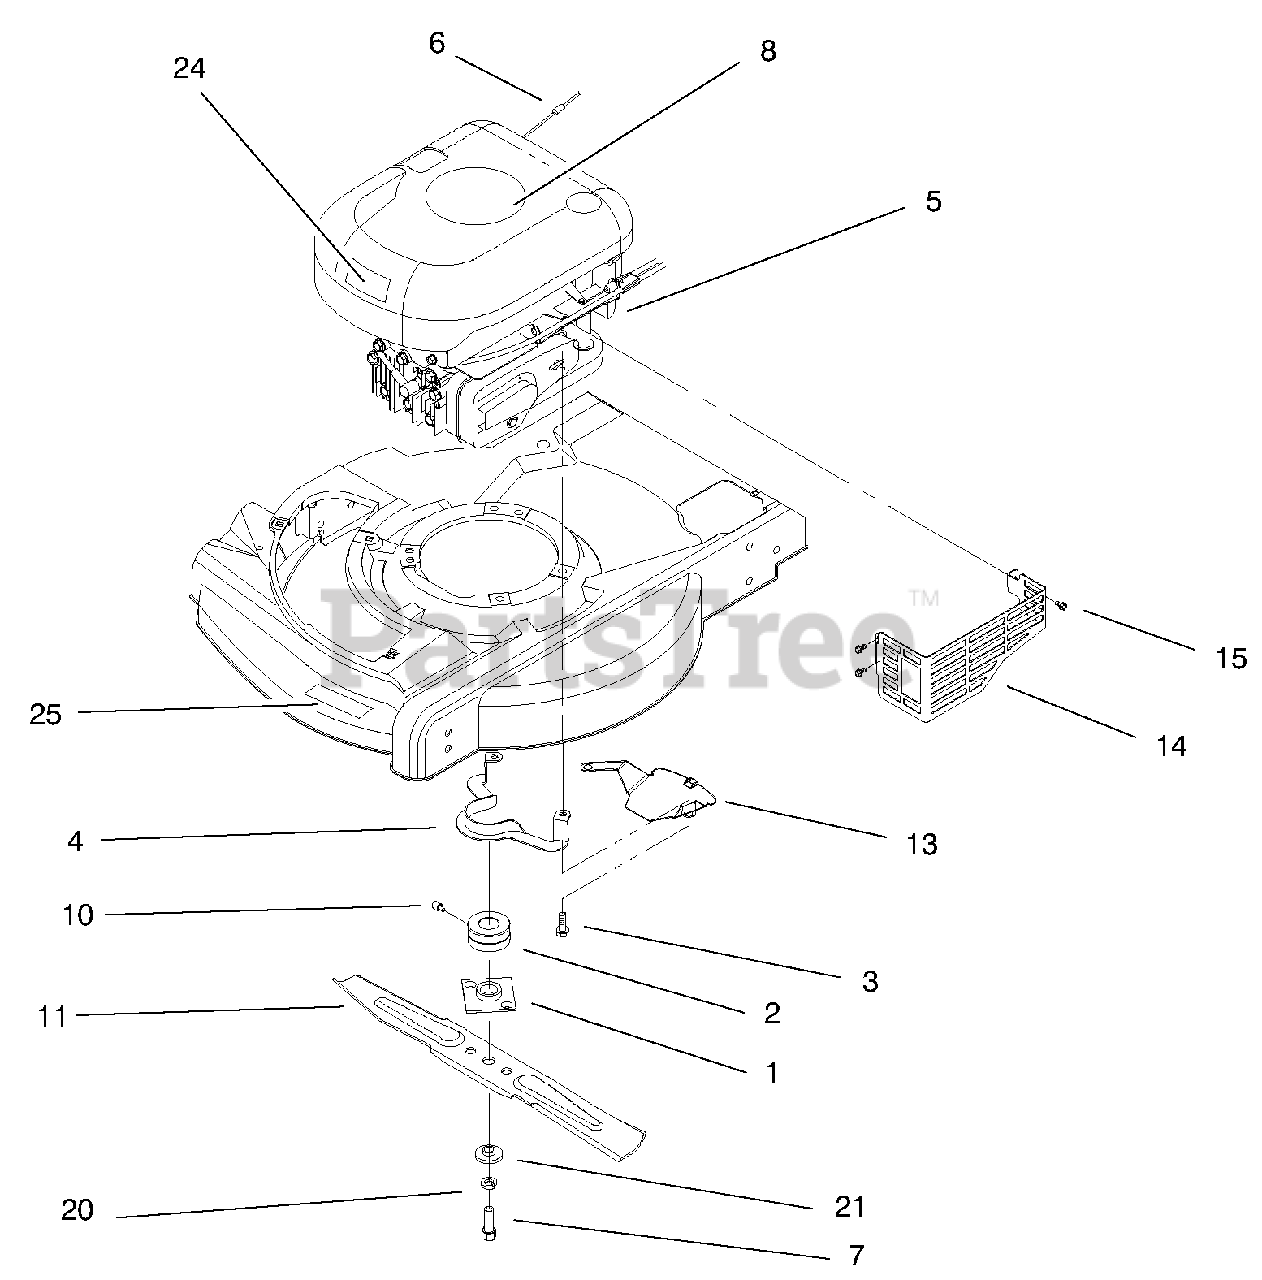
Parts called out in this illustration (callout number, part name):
1	ASM-Plate & Collar
2	Pulley-Engine
3	Screw-Engine Mount
4	Guide-Belt
5	ASM-Engine
6	Rope-Stop
7	Bolt-Blade
8	Decal-Recoil
10	Screw-Set
11	Blade-21" Whirl
13	Shield-Grass
14	Shield-Muffler
15	Screw-HWHTF
20	Washer-Lock
21	Spacer-Blade
24	Applique-Shroud
25	Decal-Deck
